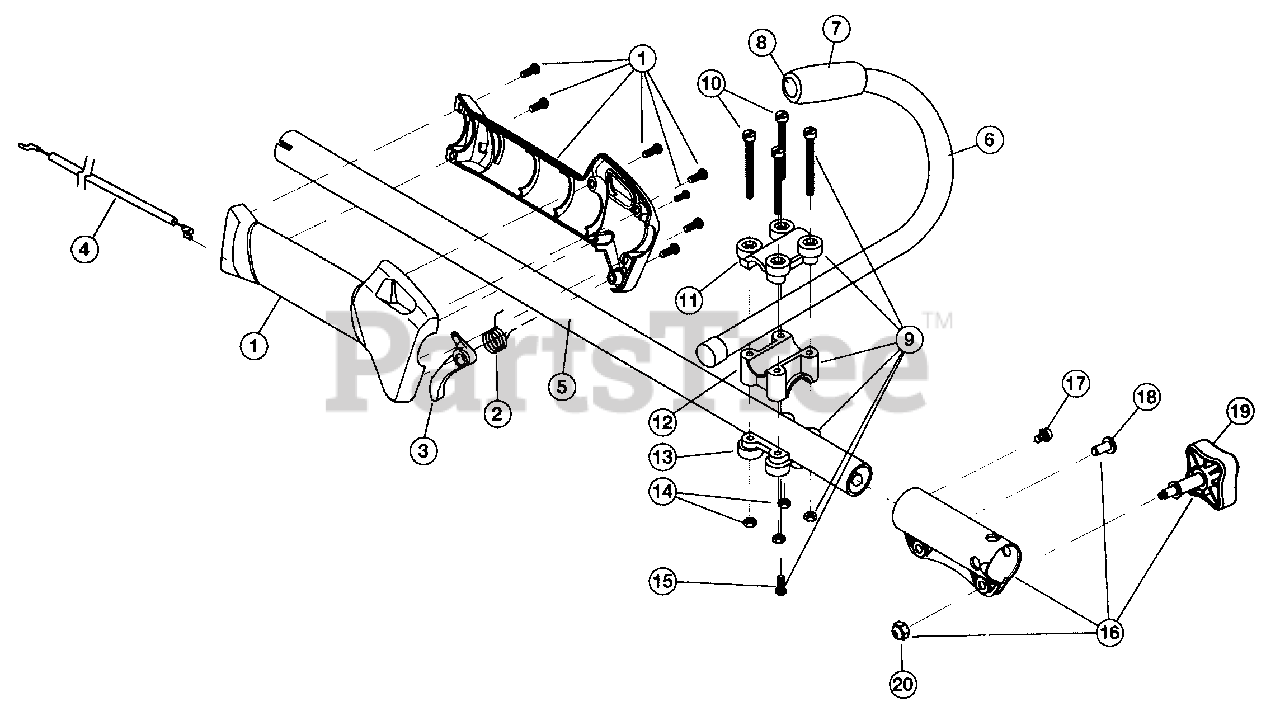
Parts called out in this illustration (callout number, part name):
1	Throttle Housing & Trigger Assembly
2	Throttle Trigger Spring
3	Throttle Trigger
4	Throttle Cable Assembly
5	Upper Drive Shaft Housing Assembly
6	J-Handle Assembly
8	Tube Closure
9	Handle Bracket Assembly
11	Upper Handle Clamp
12	Middle Handle Clamp
13	Lower Handle Clamp
15	Anti-Rotation Screw
16	Coupler
19	Adjustment Knob
20	Knob Retaining Nut
